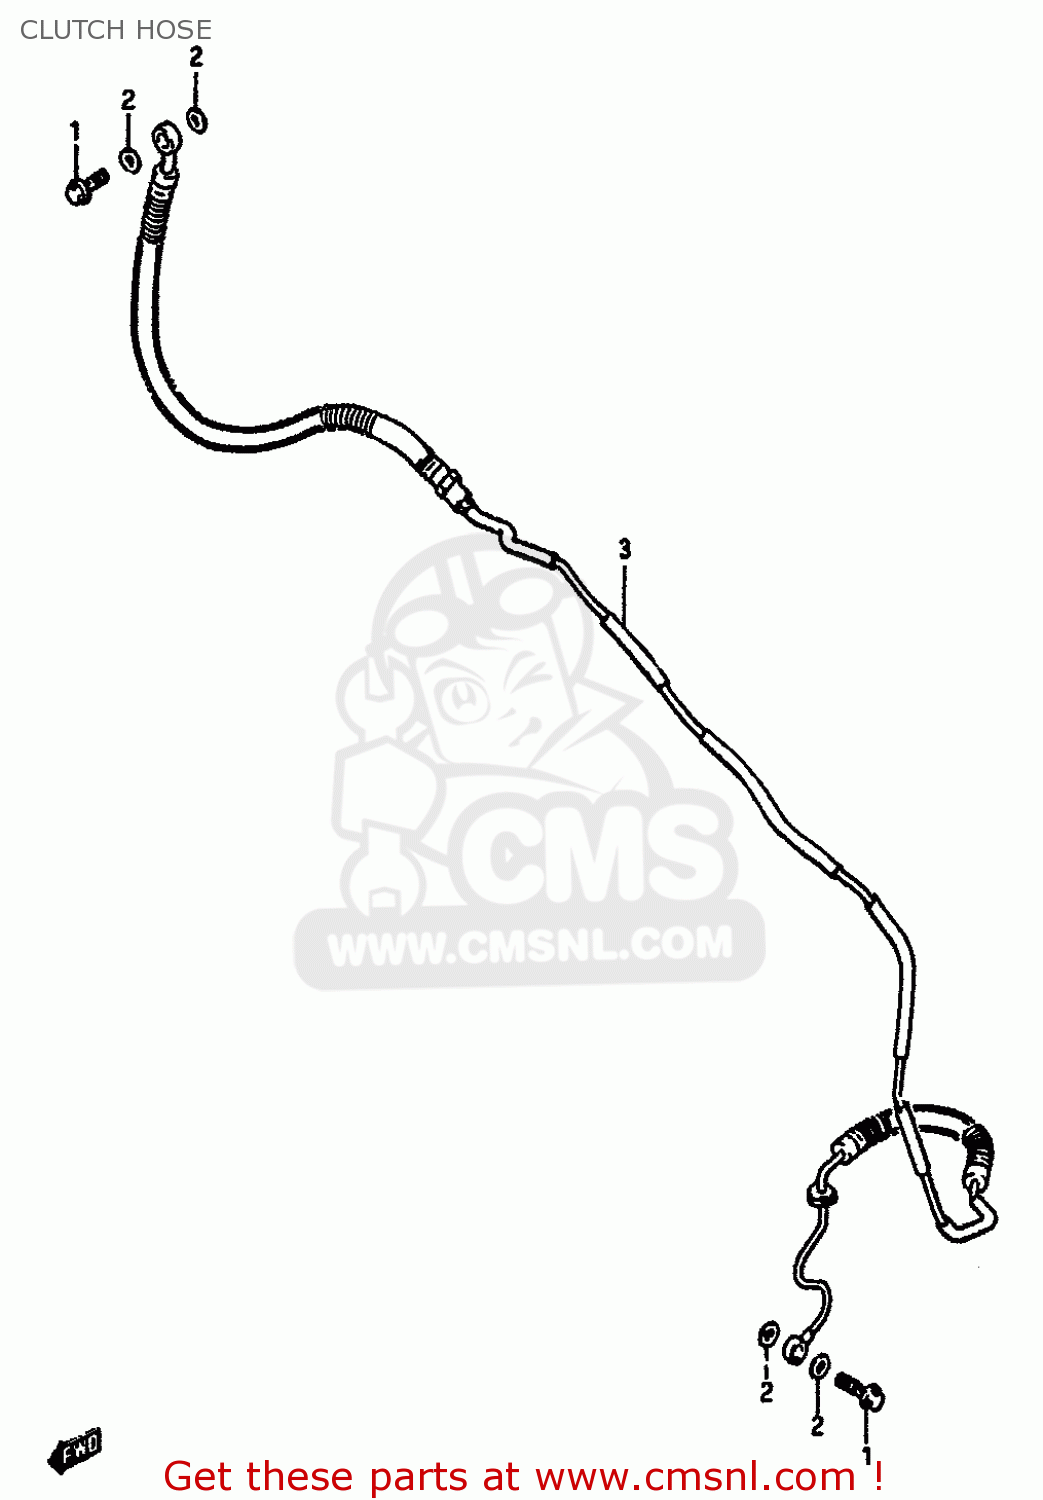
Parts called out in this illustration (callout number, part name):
1	BOLT UNION
2	WASHER(10X15X1.5)
3	HOSE ASSEMBLY,CLUTCH
